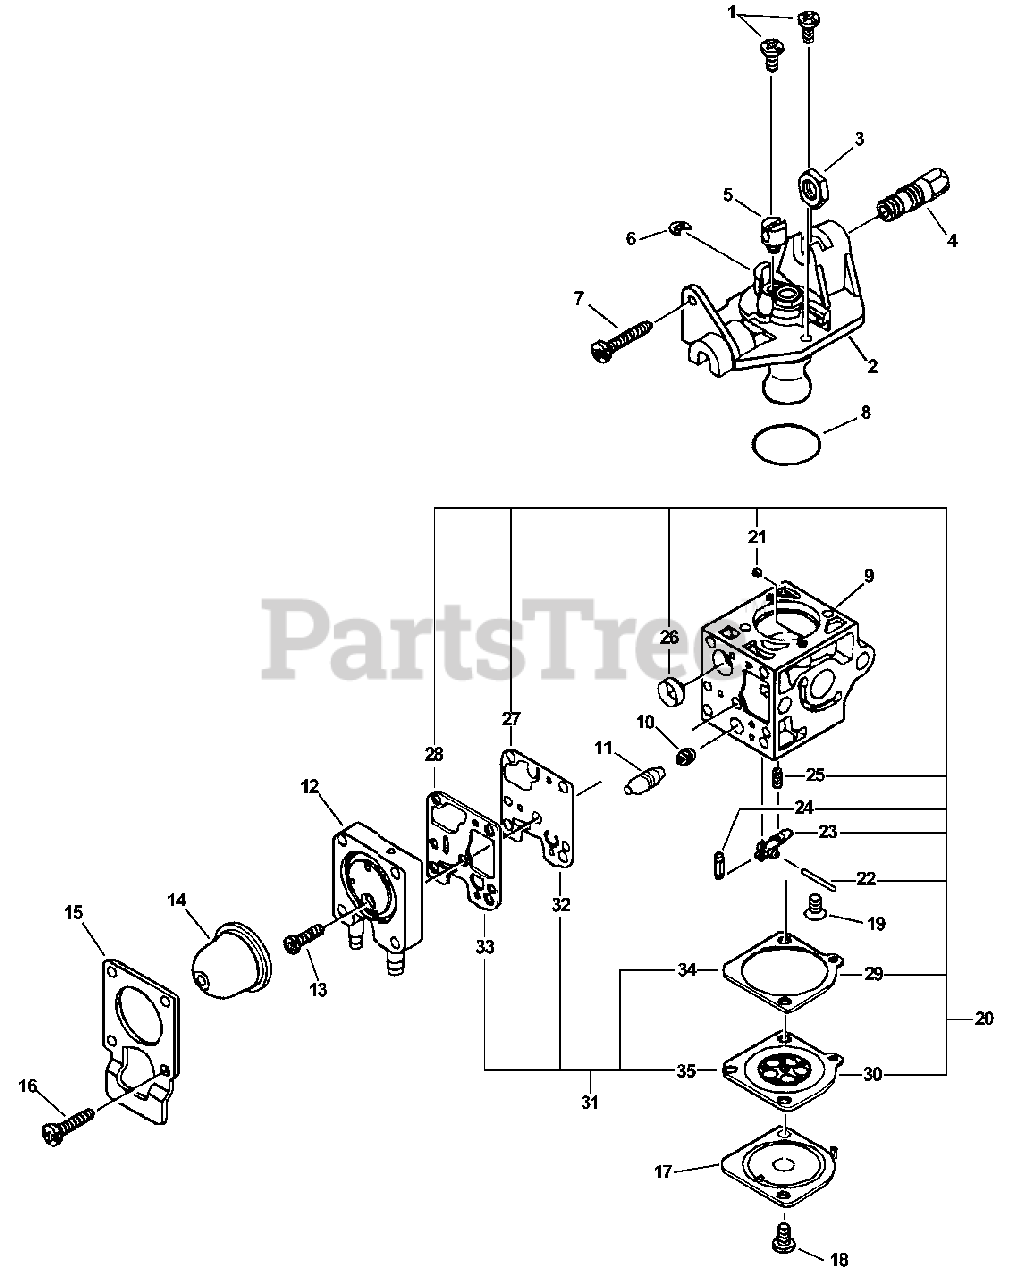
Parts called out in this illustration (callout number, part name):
2	ROTOR COVER ASSY
4	NUT, CABLE ADJUST
6	RING, RETAINING
7	SCREW, IDLE ADJUST
9	BODY, CARBURETOR
11	PLUG KIT
12	BASE, PURGE
13	SCREW, PURGE BASE
14	BULB, PURGE
15	RETAINER, PURGE BULB
16	SCREW, RETAINER
17	COVER, METERING
19	SCREW, METERING LEVER PIN
20	REPAIR KIT
21	GUIDE, ROLLER
22	PIN, METERING LEVER
23	LEVER, METERING
24	VALVE, INLET NEEDLE
25	SPRING, METERING LEVER
26	STRAINER
27	DIAPHRAGM, PUMP
28	GASKET, PUMP
29	GASKET, DIAPHRAGM
30	DIAPHRAGM, METERING
31	DIAPHRAGM/GASKET KIT
32	DIAPHRAGM, PUMP
33	GASKET, PUMP
34	GASKET, DIAPHRAGM
35	DIAPHRAGM, METERING
